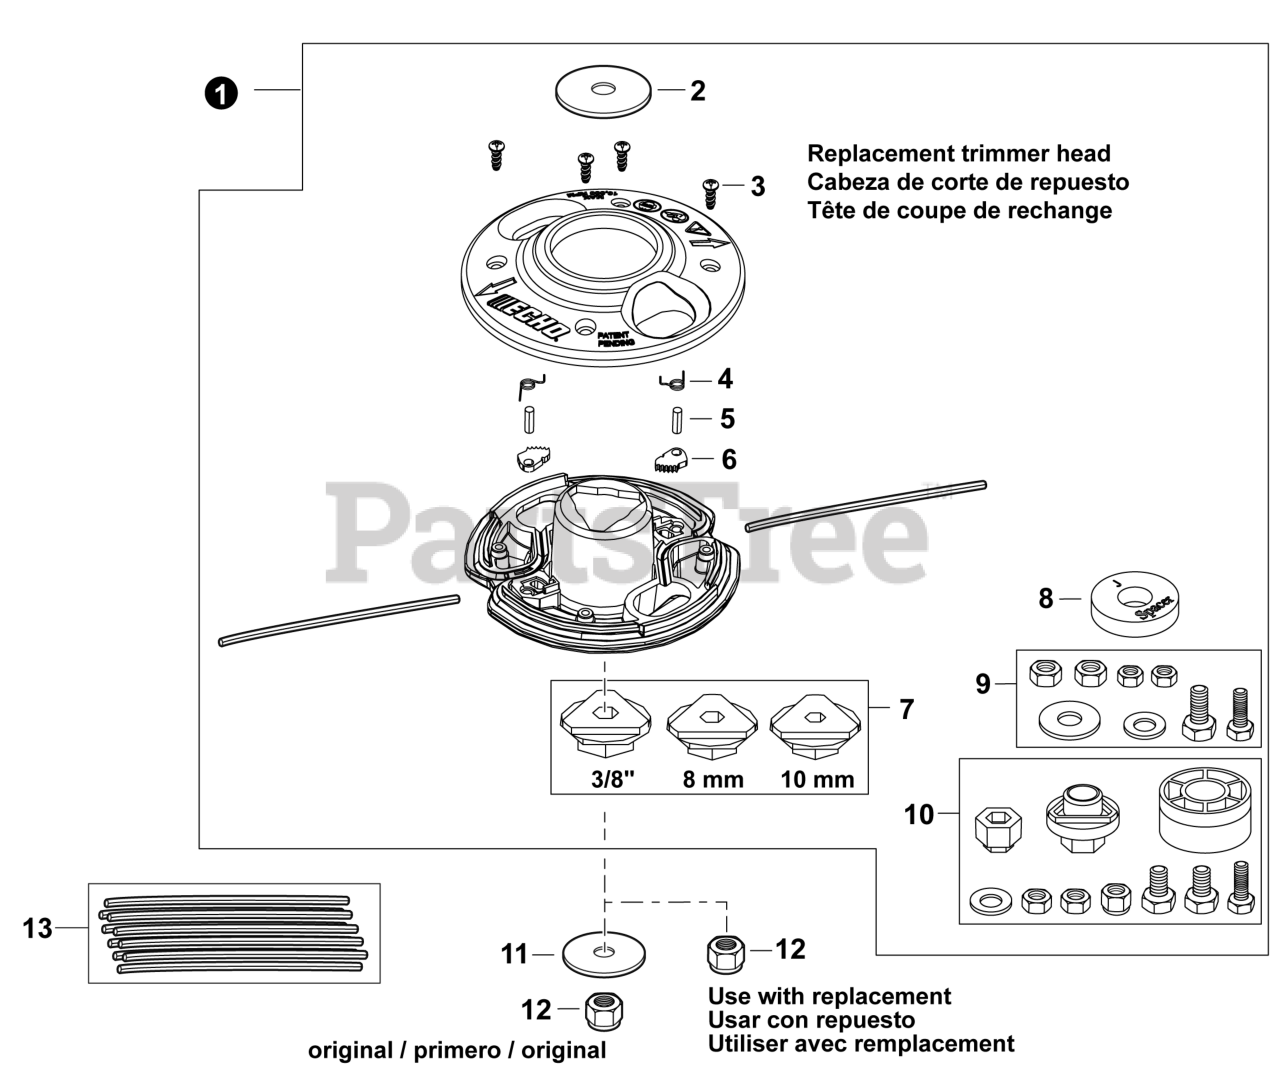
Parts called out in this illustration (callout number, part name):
1	TRIMMER HEAD - RAPID-LOADER™
2	WASHER 10
3	SCREW, TAPPING #8x0.5
4	SPRING, TORSION
5	PIN
6	PAWL
7	ADAPTOR KIT
8	SPACER
9	HARDWARE PACK
10	HARDWARE PACK
11	WASHER 10
12	NUT, LOCK
13	LINE, TRIMMER - 0.095 DIA. (PKG. OF 50)
